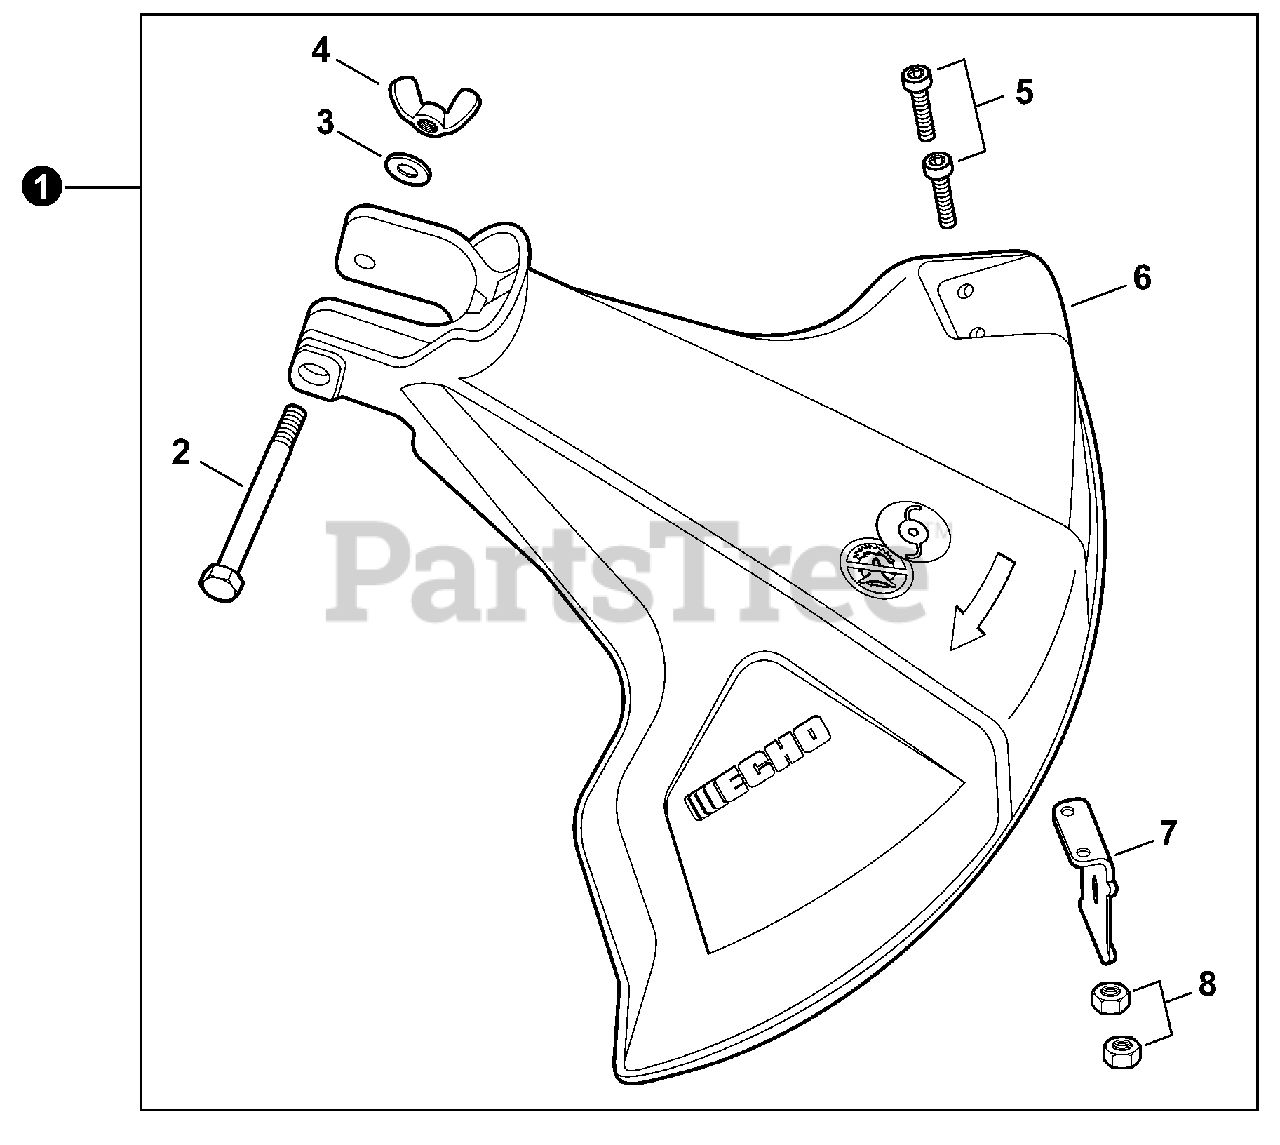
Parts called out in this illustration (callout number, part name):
1	DEBRIS SHIELD ASSY
2	BOLT 1/4"-20×2"
3	WASHER, 1/4"
4	NUT, WING 1/4"-20
5	BOLT, TORX 5×12
6	SHIELD, DEBRIS
7	CUTTER, LINE
8	NUT M5
